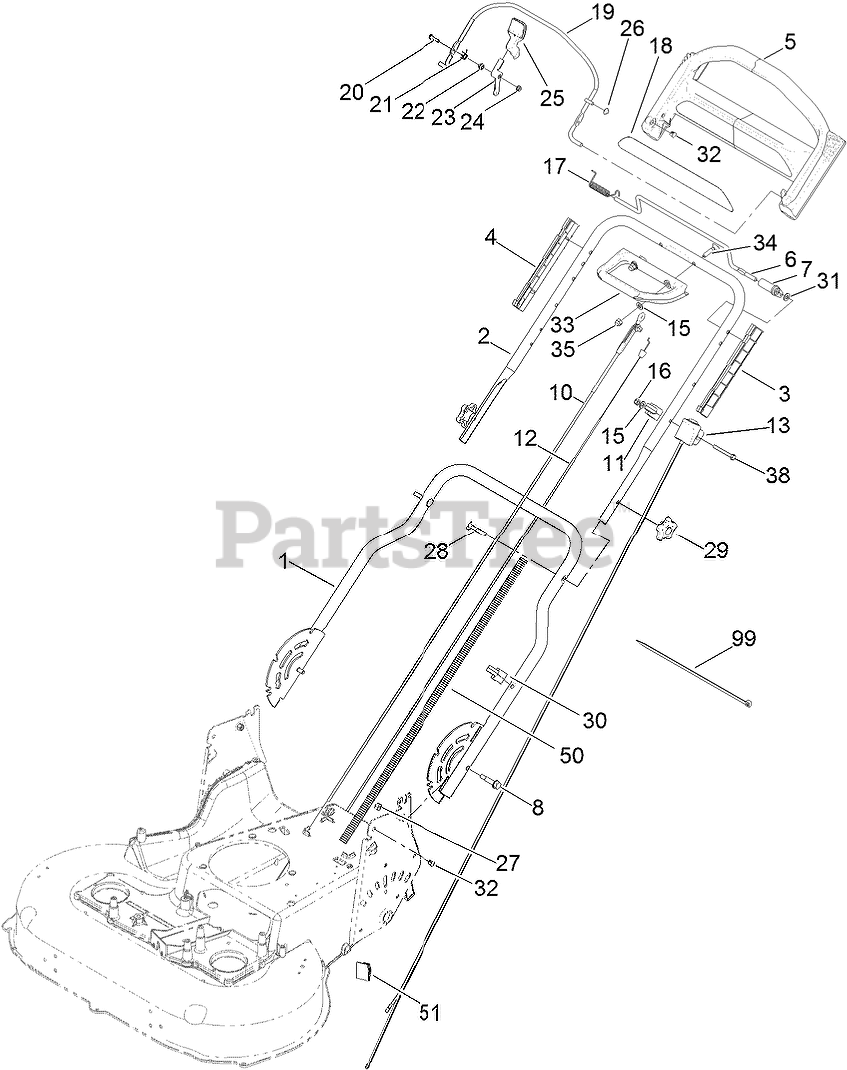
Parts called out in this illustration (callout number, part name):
1	HANDLE-LOWER
2	HANDLE-UPPER
3	GUIDE-LH
4	GUIDE-RH
5	HANDLE-CONTROL
6	BAR-CONTROL, TRACTION
7	LEVER-TRACTION
8	BOLT-SHOULDER, HHF
10	CABLE-BRAKE, BBC
11	ANCHOR-CABLE
12	CABLE-TRACTION
13	SWITCH HOUSING ASM
15	WASHER-FLAT
16	NUT-LOCK, NI
17	Spring-Torsion
18	DECAL-HANDLE
19	BAIL-BRAKE
20	SCREW-HWH
21	SPRING-TORSION
22	SPACER
23	LEVER
24	NUT-LOCK, FLANGE
26	NUT-SPEED
27	NUT-LOCK, NI
28	SCREW-HANDLE
29	KNOB-HANDLE
30	GUIDE-CABLE
31	WASHER-PLAIN
32	Plug-Dome
33	HANDLE-ASSIST, TRACTION
34	SCREW-HANDLE
35	NUT-HEX, NYLON CAP
38	SCREW-HH
50	CONDUIT-CONVOLUTED
51	CLIP-CONDUIT
99	TIE-CABLE
